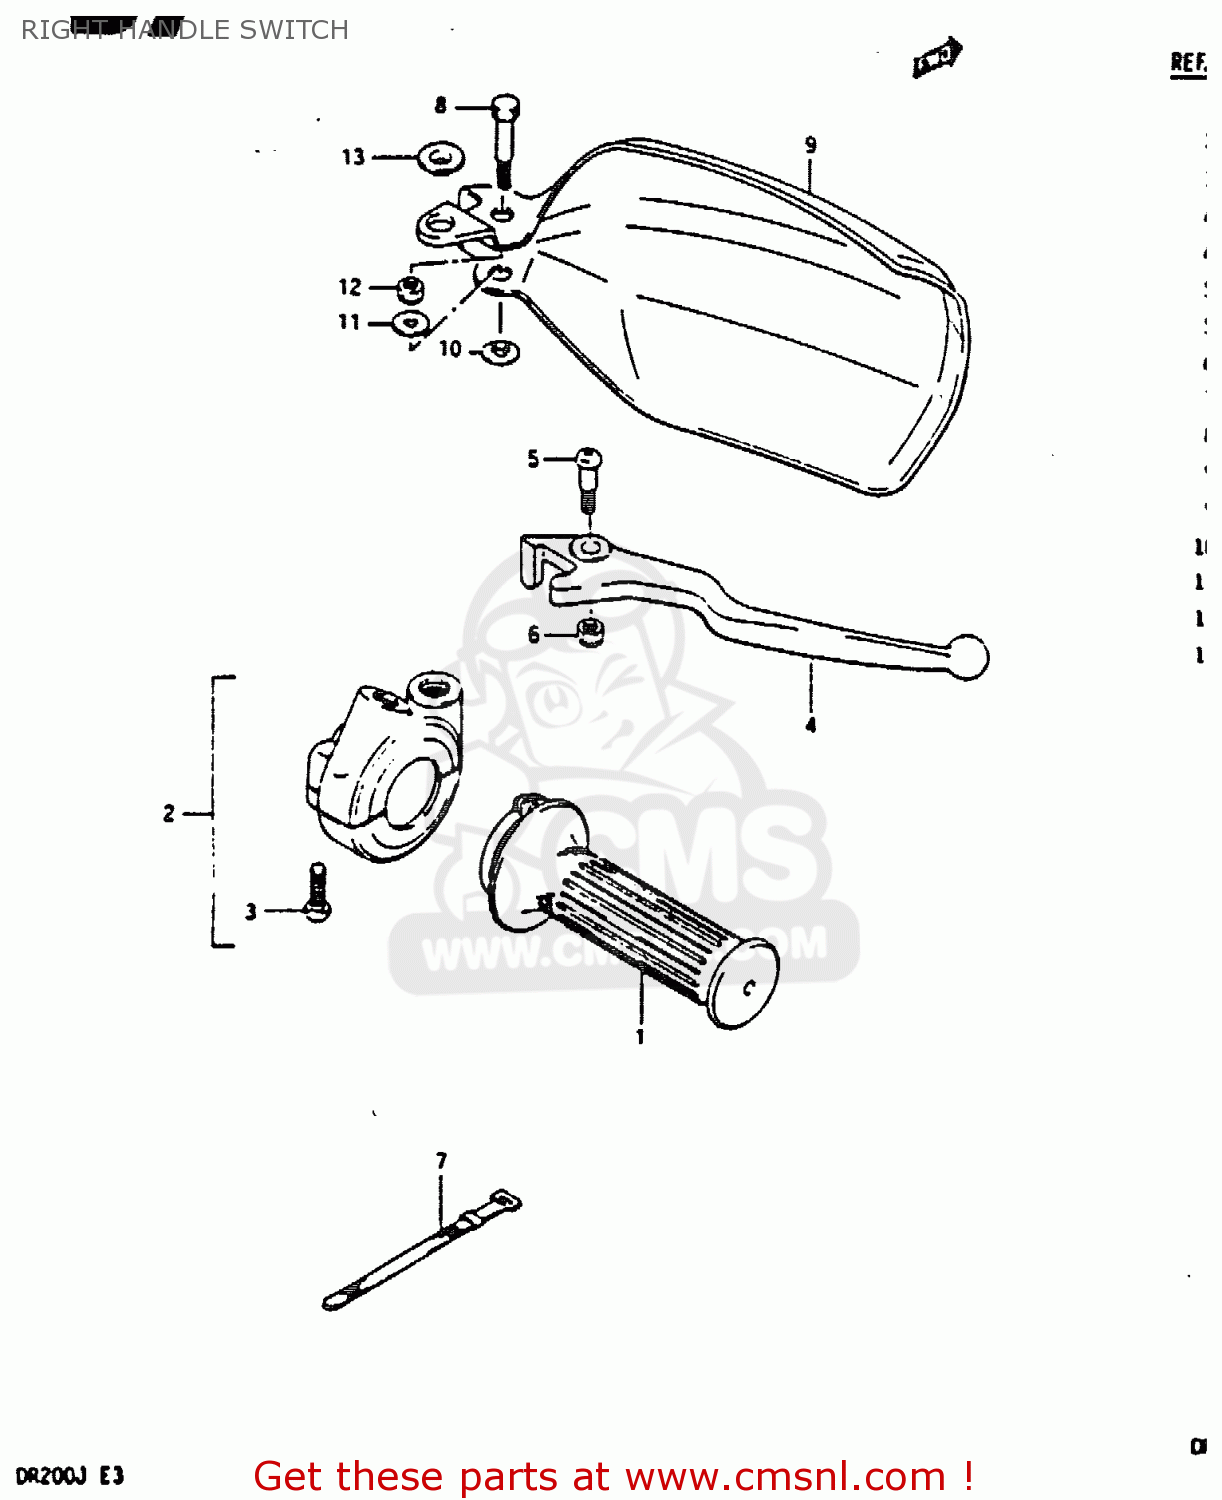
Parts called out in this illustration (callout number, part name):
1	GRIP,THROTTLE
2	CASE ASSY,THROTTLE
3	SCREW 5X20
4	LEVER,BRAKE
5	SCREW
6	NUT
7	CLAMP(L:120)
8	BOLT,LEVER PIVOT
9	COVER,KNUCKLE,RIGHT
10	WASHER
11	WASHER(6.5X16X1.2)
12	NUT 6MM
13	WASHER
